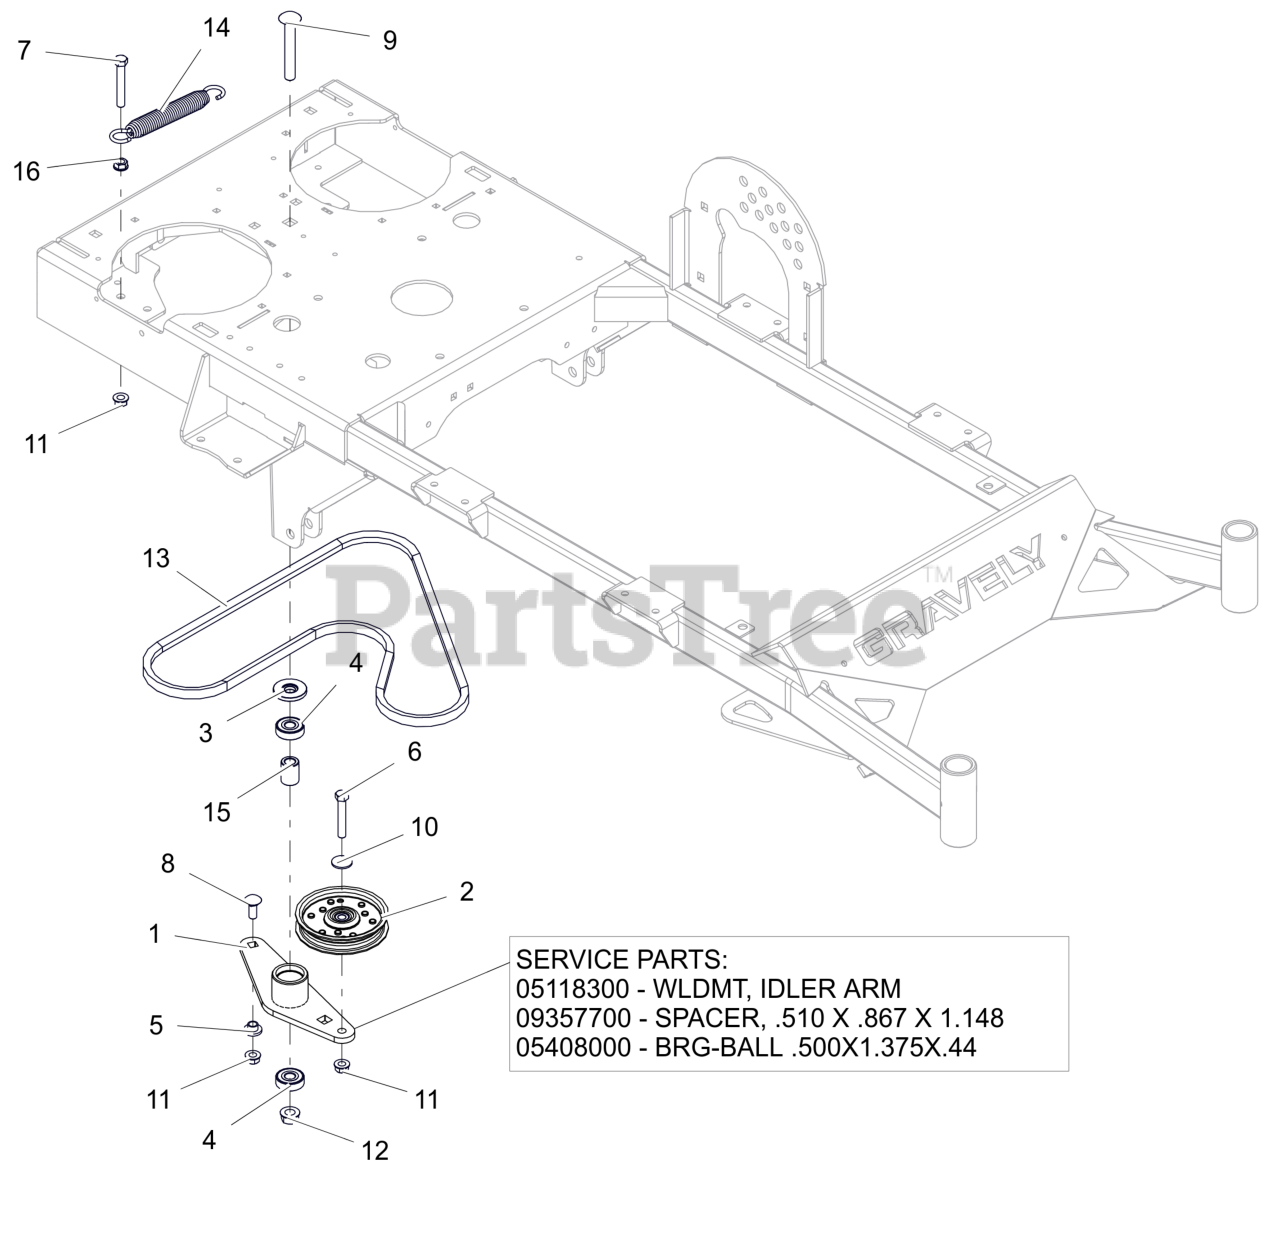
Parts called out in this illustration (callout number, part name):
1	ASM, IDLER ARM SERVICE
1	WLDMT, IDLER ARM
1	SPACER .510 X .867 X 1.1485
1	BRG-BALL .500X1.38X.437
2	ASM, 4" IDLER (.75 WIDE)
3	SPACER, IDLER ARM
4	BRG-BALL .500X1.38X.437
5	BSHG-FLG .385X.500X.875X.406
6	BLT,HEX .38-16X2.25 G5 ZCC
7	BLT, HEX .38-16X2.50 G5 ZCC
8	BLT, RHSN .38-16X1.00 G5 ZCC
9	BLT, RHSSN .50-13X3.50 G5 ZCC
10	WSHR,FLT .438X1.00X.083 ZCC
11	NUT-LK-CTR-FLG .375-16 GF ZCC
12	NUT-LK-CTR-FLG .500-13 GG ZCC
13	V-BELT, HA WRAPPED
14	SPRING- EXTENSION
15	SPACER .510 X .867 X 1.1485
16	NUT, SPNLK-FLG .38-16 G5 ZCC
